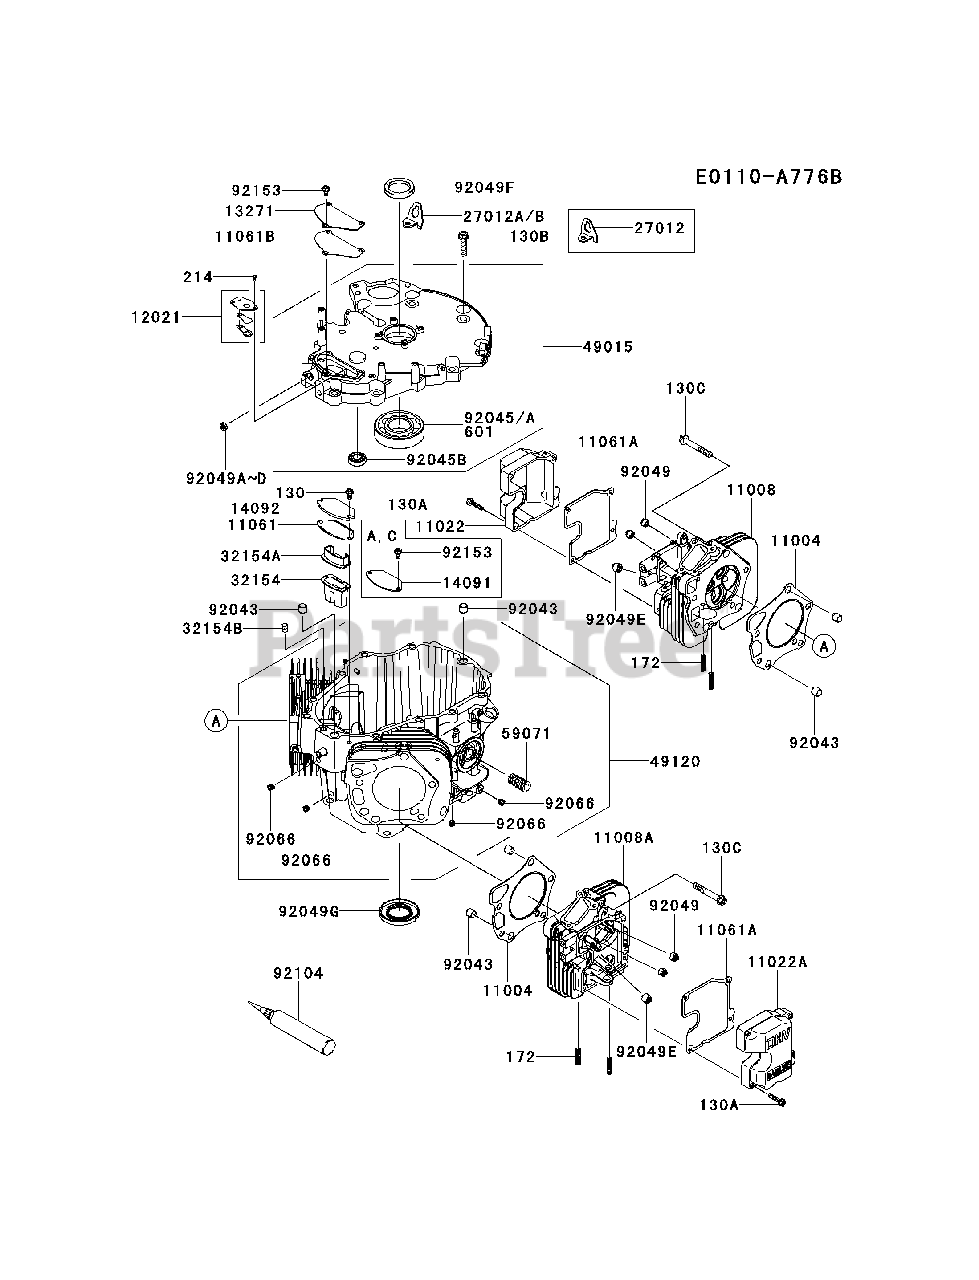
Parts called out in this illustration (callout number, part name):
130A	BOLT-FLANGED,6X30
130B	BOLT-FLANGED,10X40
130C	BOLT-FLANGED,10X65
172	BOLT-STUD,8X18
214	SCREW-PAN+-,4X8
601	BEARING-BALL
